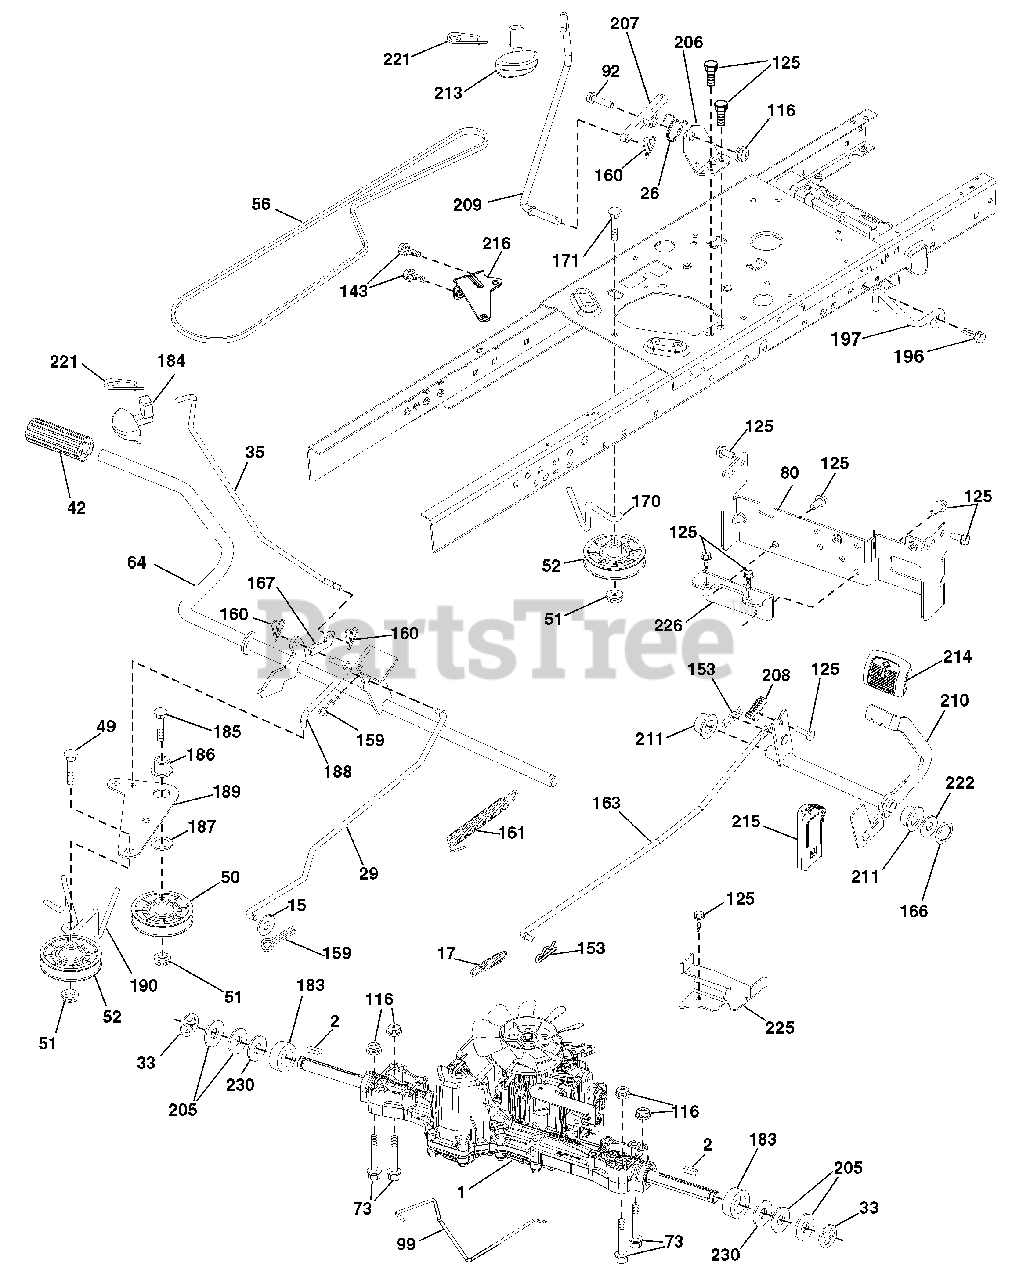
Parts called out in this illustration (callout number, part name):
1	Transaxle, TUFFTORQ K46
15	Washer 13/32 x 13/16 x 16 Ga.
17	Spring, Brake
26	Spring Return Cruise
29	Rod, Brake
35	Rod, Brake, Park
42	Cover, Foot Pedal
50	Pulley Idler Flat
51	Lock Nut 3/8-16
52	Idler V-Groove 910" Offset
56	V-Belt, Drive
64	Shaft Asm. Pedal Brake Control
73	Bolt Hex Flghd 5/16-18 Gr. 5
80	Bracket Strap Torque
92	Bolt Fin Hex 5/16-18 unc x 1.25
99	Rod Spring Bypass
116	Nut Lock Hex Flange 5/16-18
125	Screw 5/16-18 x 3/4
143	Screw 5/16-18 x 1/2
153	Retainer Spring
159	Pin Cotter 1/8 x 3/4
160	Retainer Clip
161	Spring, Return, Clutch
163	Rod Pedal Control
166	Nut Push
167	Latch Brake Parking
170	Keeper Belt Centerspan
171	Bolt RDHD SQNK 3/8-16UNC x 2
183	Spacer Split
184	Handle Parking Brake
185	Bolt Rdhd Sqnk 3/8-16 x 2-1/2
186	Spacer Retainer
187	Washer
188	Link Clutch Ground Drive
189	Bellcrank Ground Drive
190	Keeper Bellcrank Ground Drive
196	Screw 3/8-16 x 1
197	Bracket Clutch Anti-Rotation
206	Bracket Mount Latch Cruise
207	Latch Control Cruise
208	Gear Sector Control Cruise
209	Rod Control Cruise
210	Rocker Asm. Pedal Control
211	Bearing Nylon
213	Knob Control Cruise
214	Pedal Forward
215	Pedal Reverse
216	Bracket Pulley Idler
221	Retainer Spring Clip Handle
222	Washer 21/32 x 1-1/4 x 10 Ga.
225	Keeper Belt Trans.
226	Bracket Mount Touque
230	Washer Hardened
